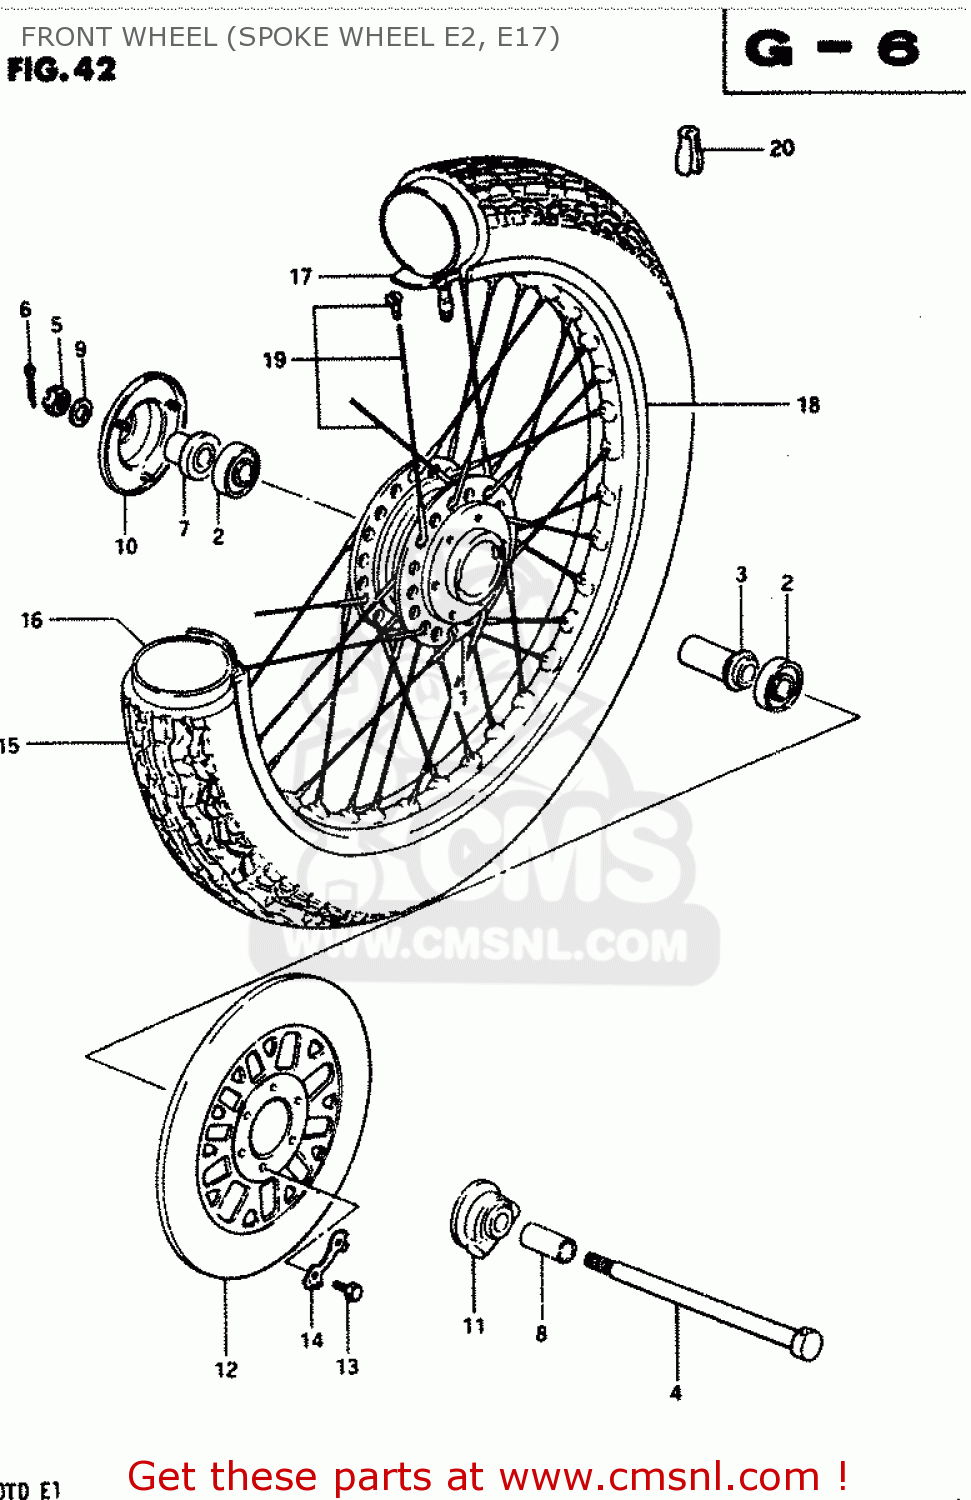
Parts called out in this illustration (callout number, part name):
1	DRUM,FRONT HUB
2	BEARING
3	SPACER,FR HUB BEARING
4	AXLE,FRONT
5	NUT 12MM
6	COTTER PIN
7	SPACER,FR HUB BEARING,R
8	SPACER(15X22X30)
9	WASHER
10	COVER,FR HUB,R
11	BOX ASSEMBLY,SPEEDOMETER GEAR
12	DISC,FR BRAKE
13	BOLT(8X25)
14	WASHER
15	TIRE (90/90-19) IRC
16	TUBE 2.75-19 070-483MM
17	PROTECTOR,WHL INR TUBE
18	RIM,FR WHEEL
19	SPOKE ASSY,FR
20	BALANCER,WHEEL (B)
